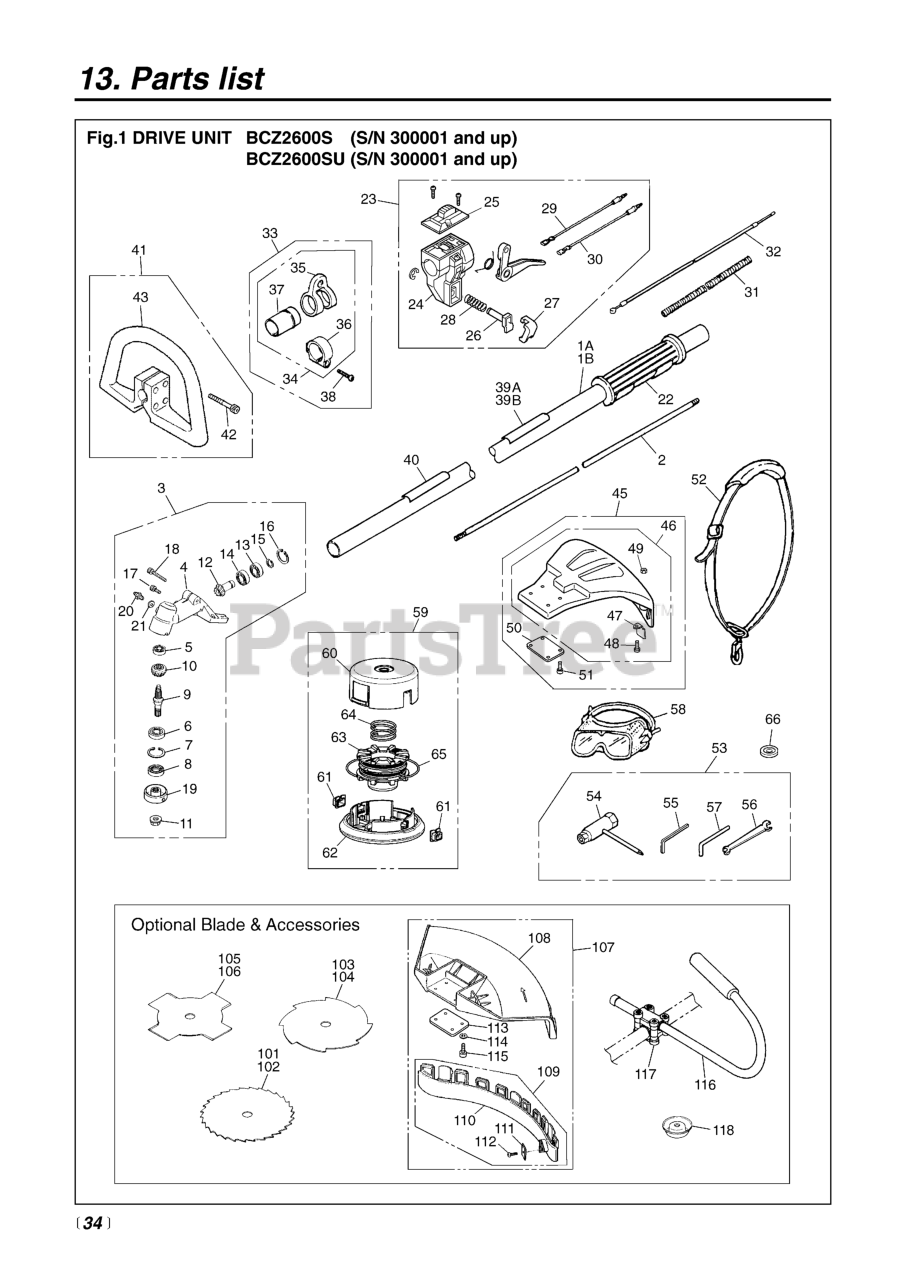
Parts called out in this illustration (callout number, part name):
1A	PIPE COMP (REPLACES -12100)
1B	PIPE COMPLETE
2	SHAFT (RPLS -12212)
3	GEARCASE ASSY (RPLS -13000)
4	GEARCASE
7	RING, SNAP, M26 X 1.2
8	SEAL, OIL
9	SHAFT
10	GEAR
11	NUT
12	PINION
16	RING, SNAP, M24 x 1.2
17	BOLT, M5 X 10
18	BOLT
19	HOLDER (A)
20	FITTING, GREASE
21	WASHER, M6 X .8
22	GRIP (RPLS 3577-32140 & 3220-
24	LEVER (USE 848-8R2-0313)
29	CORD (A), BLACK
30	CORD (B), RED
31	TUBE (RPLS 4900-72141)
32	CABLE (RPLS 5580-83100)
33	HANGER ASSEMBLY
34	HANGER COMPLETE
35	HANGER
36	CLAMP
37	SLEEVE
38	SCREW, M5 x 25
39A	PLATE, NAME
39B	PLATE, NAME (NLA)
40	PLATE, CAUTION
41	HANDLE ASSY.
42	HANDLE T
43	SCREW, M5 x 30
45	GUARD ASSY (RPLS -24000)
46	GUARD COMP (RPLS. -24100)
47	BLADE (RPLS T3002-24120)
48	SCREW
49	NUT
50	PLATE
51	BOLT (USE 3310-31720)
54	SOCKET
55	WRENCH (TOOL)
56	SPANNER, 8 X 10 (RPLS 2540- )
57	BAR
58	GOGGLE
59	TAP HEAD COMP.
60	CASE (REPLACES -15111)
61	EYELET
62	COVER (REPLACES -15131)
63	HOLDER, CORD (REPLACES-15141)
64	SPRING
65	CORD
66	HOLDER (B)
101	BLADE, 9
102	BLADE, 9
103	BLADE, 8
104	BLADE, 9
105	BLADE, 8
106	BLADE, 9
107	GUARD ASSEMBLY
108	GUARD
109	PLATE COMPLETE
110	PLATE
111	BLADE
113	PLATE
114	WASHER, SPRING M4 x 1.3
115	BOLT, M5 X 16
116	HANDLE, J
117	BRACKET ASSY (REPLACES -14100)
118	COVER
